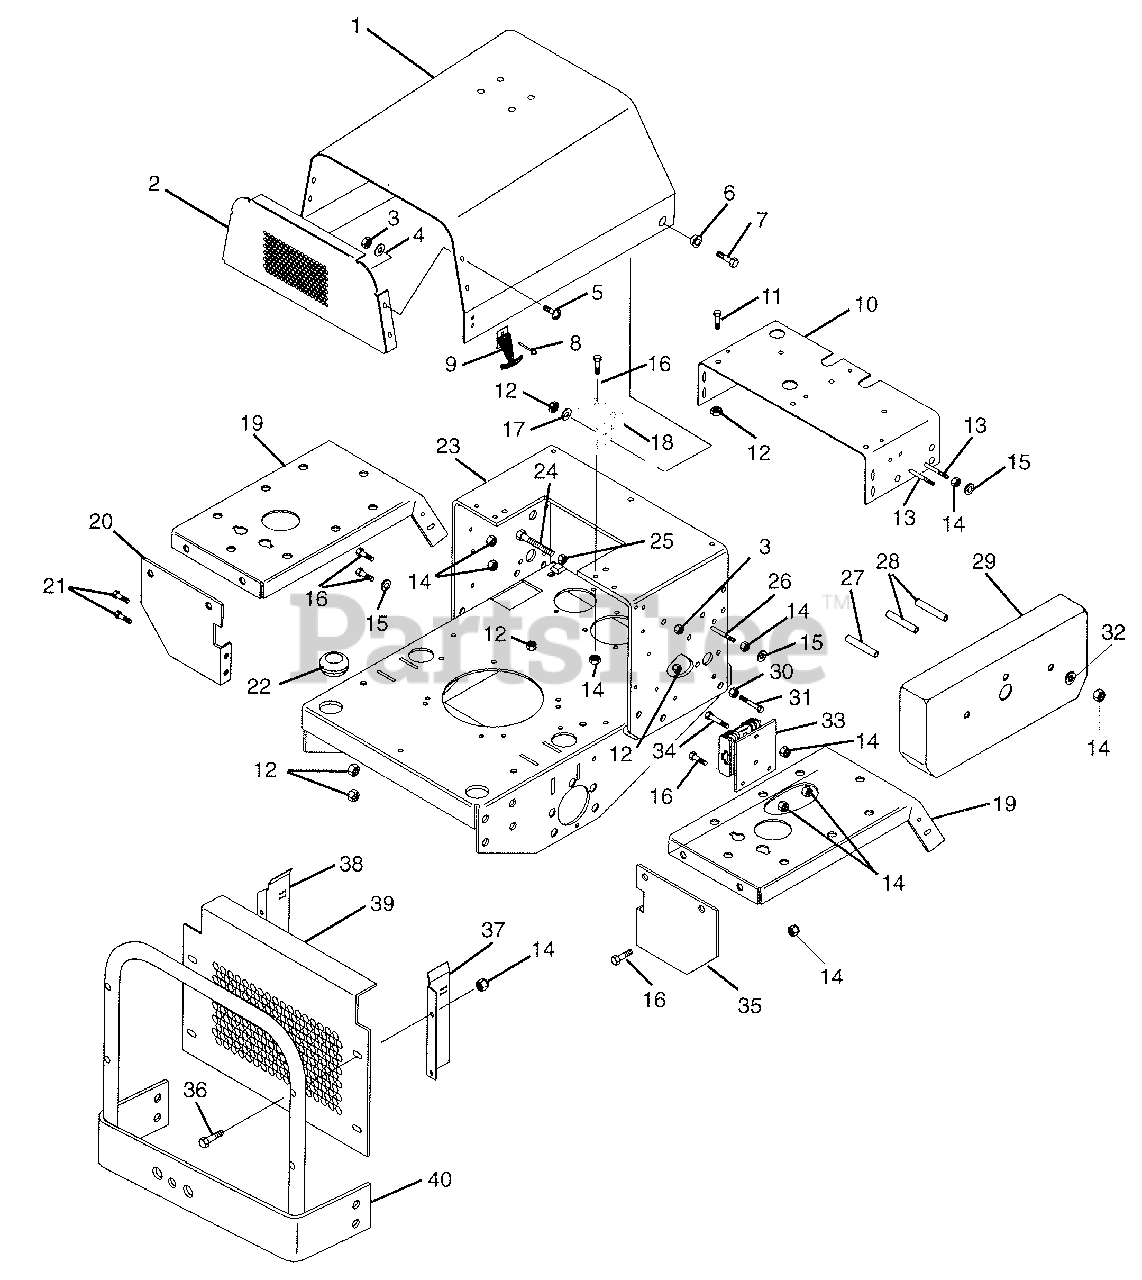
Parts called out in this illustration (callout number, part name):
1	Cover, Engine (010, 011)
2	Grille, Hood (010, 011)
3	Nut-Locking-Nylon .250-20 Grade 2 (007, 008, 009, 012, 302)
4	Washer-Flat-Steel .281 X .620 X .065 (010, 011)
5	Screw Machine .25-20 (010, 011)
6	Bushing Flange .406 X .88 X .270 X .140 (010, 011)
7	Bolt Hex .38-16 X 1.00 Grade 5 (010, 011)
8	Rivet .125 X .245 (010, 011)
9	Latch, Flexible (010, 011)
10	Panel, Silkscreen
11	Bolt Hex .38-16 X 1.00 Grade 5
12	Nut Locking Nylon .375-16 Grade 2 (007, 008, 009, 012, 302)
13	Bolt Hex .31-18 X 4.00 Grade 5
14	Nut Locking Nylon .312-18 Grade 2 (007, 008, 009, 012, 302)
15	Washer Flat Steel .344 X .688 X .065
16	Bolt Hex .31-18 X .75 Grade 5 (007, 008, 009, 012, 302)
17	Washer Flat Steel .406 X .812 X .065 (010, 011)
18	Bracket, Hood Mounting RH (010, 011)
19	Fender PM200
20	Support Fender LH
21	Bolt Hex .38-16 X 1.25 Grade 5
23	Weldment, Frame PM200
24	Bolt Hex .25-20 X 3.00
25	Nut .250-20
26	Bolt Hex .31-18 X 3.75 Grade 2
27	Spacer, Split Rolled
28	Spacer, Split Rolled
29	Guard, Linkage
30	Nut Hex .375-16 Grade 2
31	Bolt Hex .38-16 X 3.00
32	Washer Flat Steel .313 X .875 X .065
33	Plate, Regulator Rectifier Mounting (010, 011)
34	Bolt Hex .31-18 X 1.25 Grade 5 (010, 011)
35	Support, Fender RH
36	Bolt Hex .31-18 X 1.50 Grade 5 (010, 011)
37	Bracket, Hood Latch RH (010, 011)
38	Bracket, Hood Latch LH (010, 011)
39	Bracket, Hood Support (010, 011)
40	Weldment, Rear Guard
